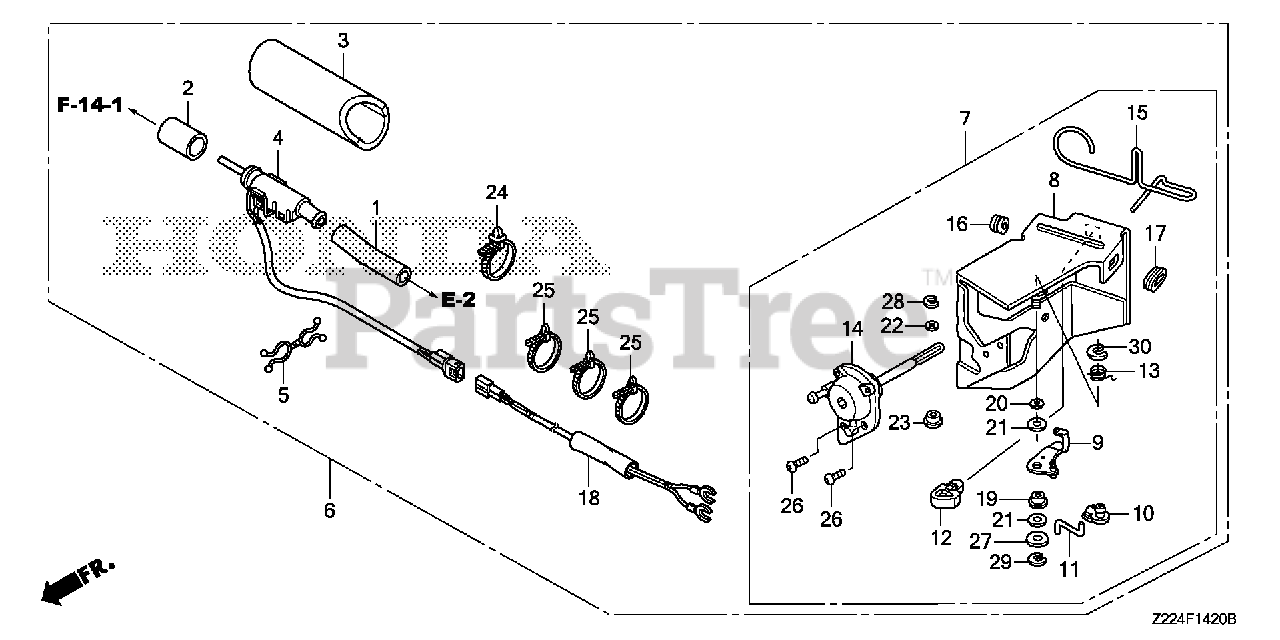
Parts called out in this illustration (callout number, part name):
1	TUBE A, BREATHER
2	TUBE B, BREATHER
3	INSULATOR S, BREATHER TUBE
4	HEATER ASSY., BREATHER (S)
5	CLIP, WIRE HARNESS
6	HEATER KIT, BREATHER
7	STAY ASSY., MANUAL CHOKE
8	STAY, DIAPHRAGM
9	LEVER, CHOKE
10	JOINT, ROD
11	ROD, CHOKE
12	STOPPER, CHOKE ROD
13	SPRING, MANUAL CHOKE
14	DIAPHRAGM ASSY.
15	ROD, CHOKE CONTROL
16	GROMMET, CHOKE ROD
17	GUIDE, CHOKE ROD
18	SUB-WIRE ASSY.
19	BUSH, ARM PIVOT
20	WASHER, CHOKE LEVER
21	SEAL, CHOKE LEVER
22	WASHER, THRUST (2.7X8)
23	COLLAR, LEVER
24	BAND, HARNESS (98MM) (NATURAL)
25	TIE, CABLE (NATURAL 225X5.0)
26	SCREW, PAN (5X12)
27	WASHER, PLAIN (5MM)
28	E-RING (2MM)
29	E-RING (4MM)
30	E-RING (7MM)
